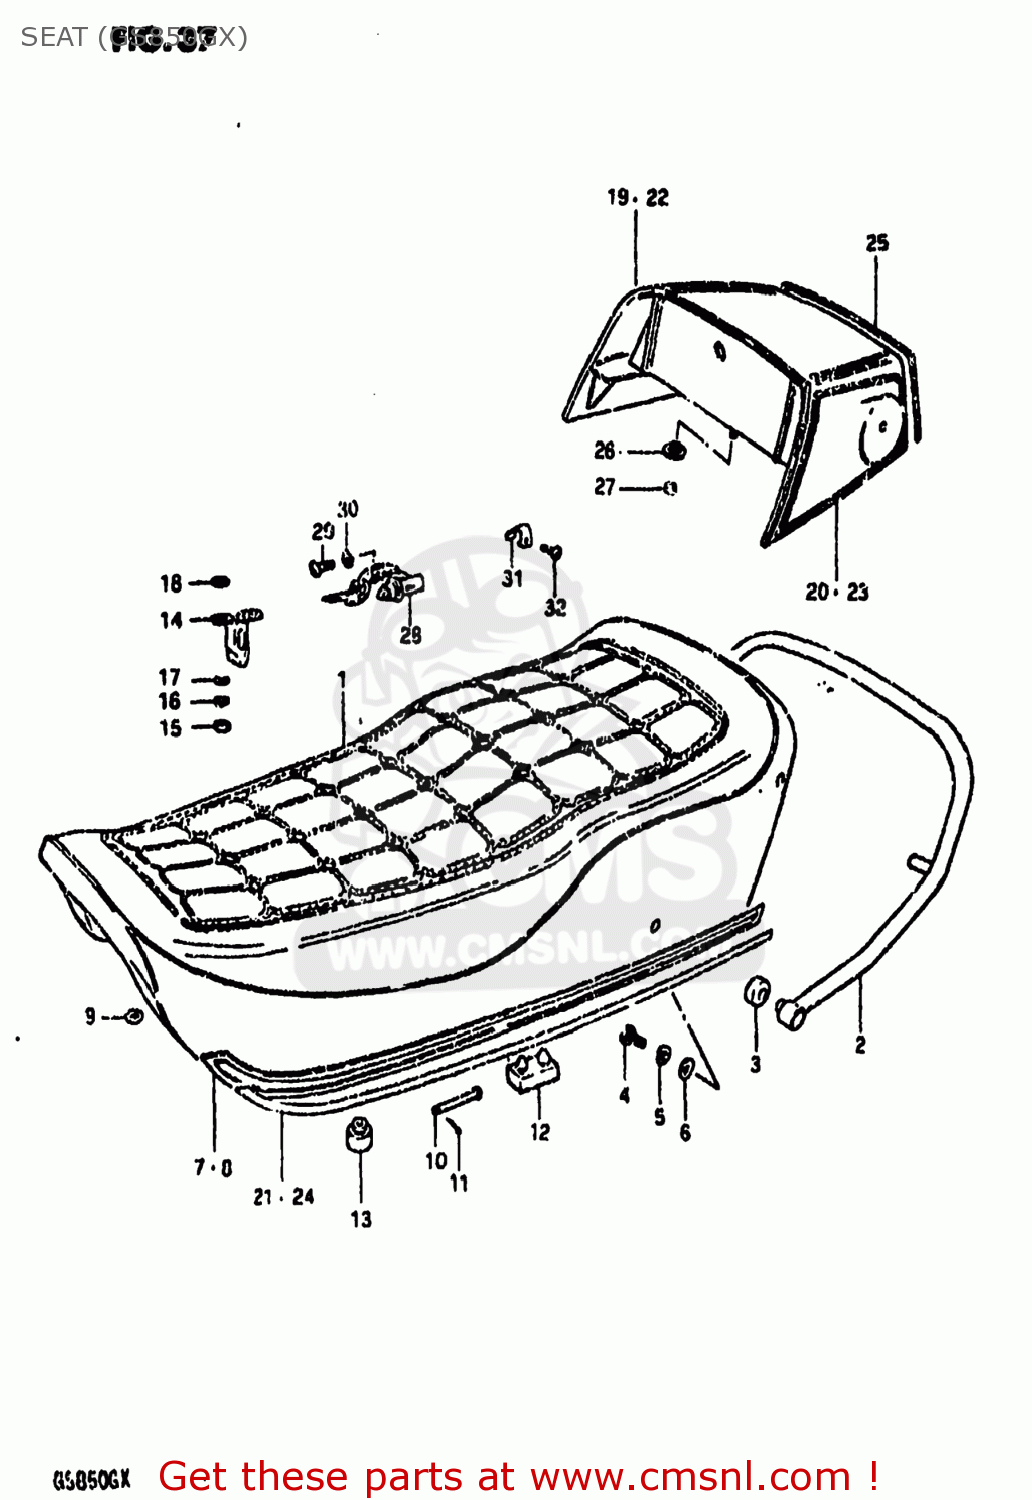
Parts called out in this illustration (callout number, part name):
1	SEAT ASSEMBLY
2	HANDLE,PILLION RIDER
3	CUSHION
4	BOLT
5	LOCK WASHER
6	WASHER
7	MOLE,R
8	MOLE,L
9	NUT
10	PIN
11	PIN
12	CUSHION
13	CUSHION
14	STRIKER,SEAT LOCK
15	NUT
16	LOCK WASHER
17	WASHER
18	WASHER (6.5X20X1.2)
19	BOX SET,SEAT TAIL
20	TAPE SET,SEAT TAIL COVER
21	TAPE SET,SEAT MOULDING
22	BOX SET,SEAT TAIL
23	TAPE SET,SEAT TAIL COVER
24	TAPE SET
25	MOLDING,SEAT TAIL COVER
26	WASHER
27	NUT 6MM
28	LOCK ASSY,SEAT
29	SCREW
30	LOCK WASHER
31	SPRING,HELMET HOLDER
32	SCREW
